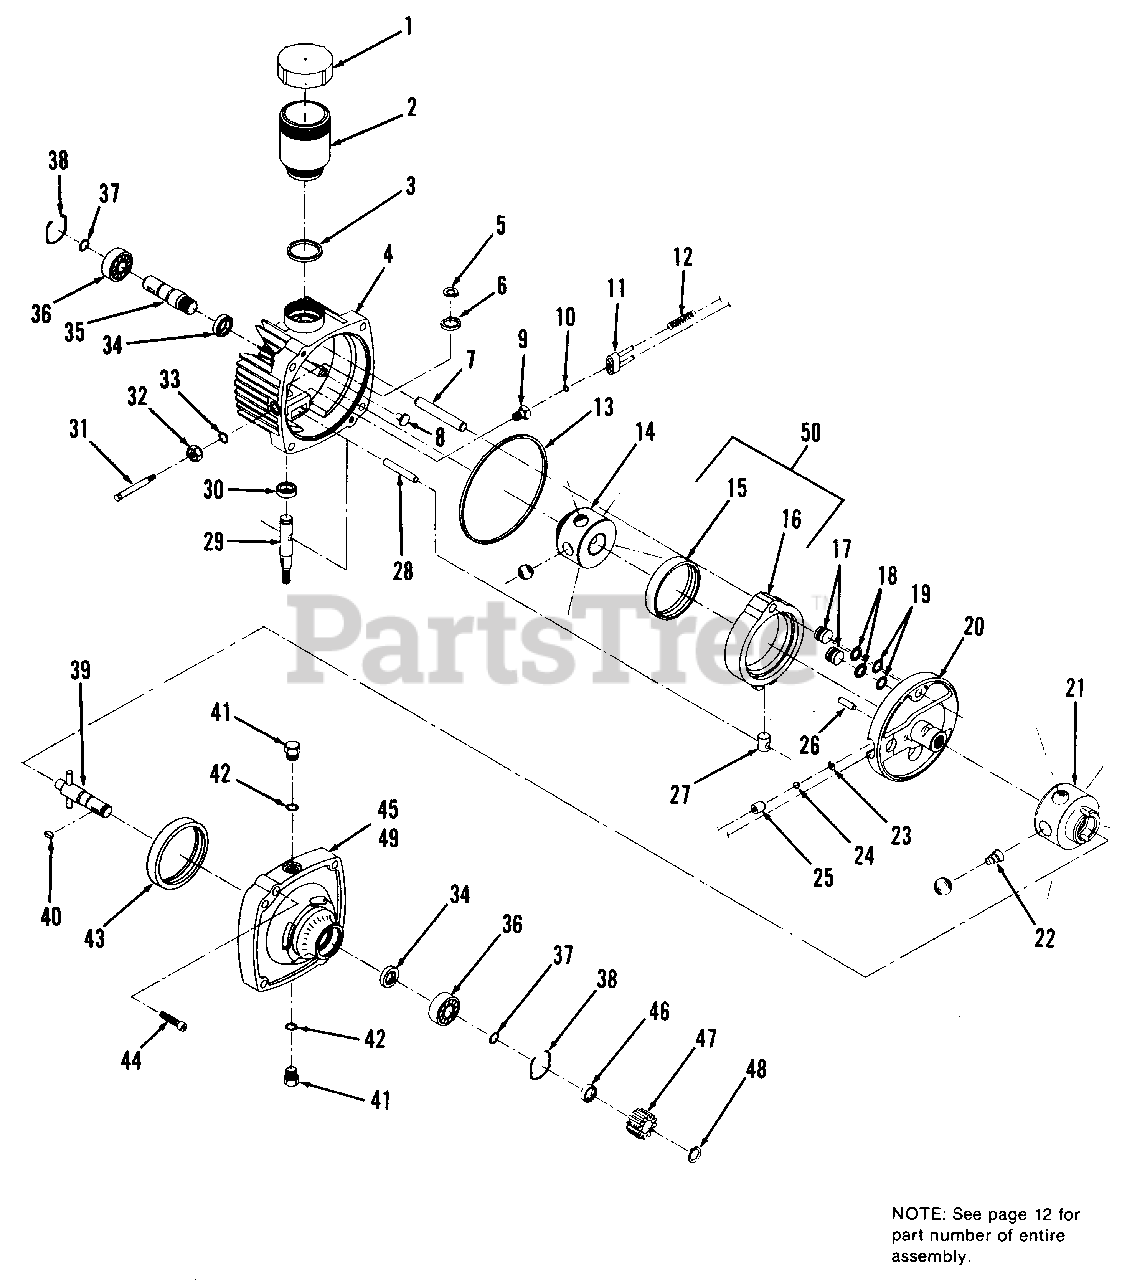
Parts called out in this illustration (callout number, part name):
1	RESERVOIR COVER, Sub-Assy.
2	RESERVOIR BODY
3	SEAL RING, Square Cut
4	COVER, Service Kit (Includes Ref. Nos. 5, 6, 7, 28, 29, 30 & 34)
5	RING, External Retaining
6	WASHER, Control Shaft
9	FITTING GUIDE, O-Ring S.A.
11	BRACKET, Pins, Sub-Assy.
12	SPRING, Valve
13	SEAL RING, Square Cut
14	PUMP ROTOR, Ball, Sub-Assy.
20	PINTLE, Sub-Assy. (Includes Ref. Nos. 17, 18, 19, 23, 24, 25 & 26)
21	MOTOR ROTOR, Ball, Sub-Assy. (Includes Qty. 5 of Ref. No. 22)
22	SPRING, Piston
27	CAM RING, Insert
31	SHAFT, Dump Valve
32	NUT, Gasket, Sub-Assy.
35	SHAFT, Input
36	BEARING, Ball (Input)
38	RING, Retaining
39	OUTPUT SHAFT, Sub-Assy.
40	* KEY, Woodruff
41	O-RING, Plug, Sub-Assy.
42	TUBE FITTING, O-Ring
44	CAPSCREW, Socket Hd.
48	RING, External Retaining
49	BODY, Sub-Assy. (Includes Ref. Nos. 34, 36, 37, 38, 39, 43 & 45)
50	CAM RING, Sub-Assy. (Includes Ref. Nos. 15 & 16)
